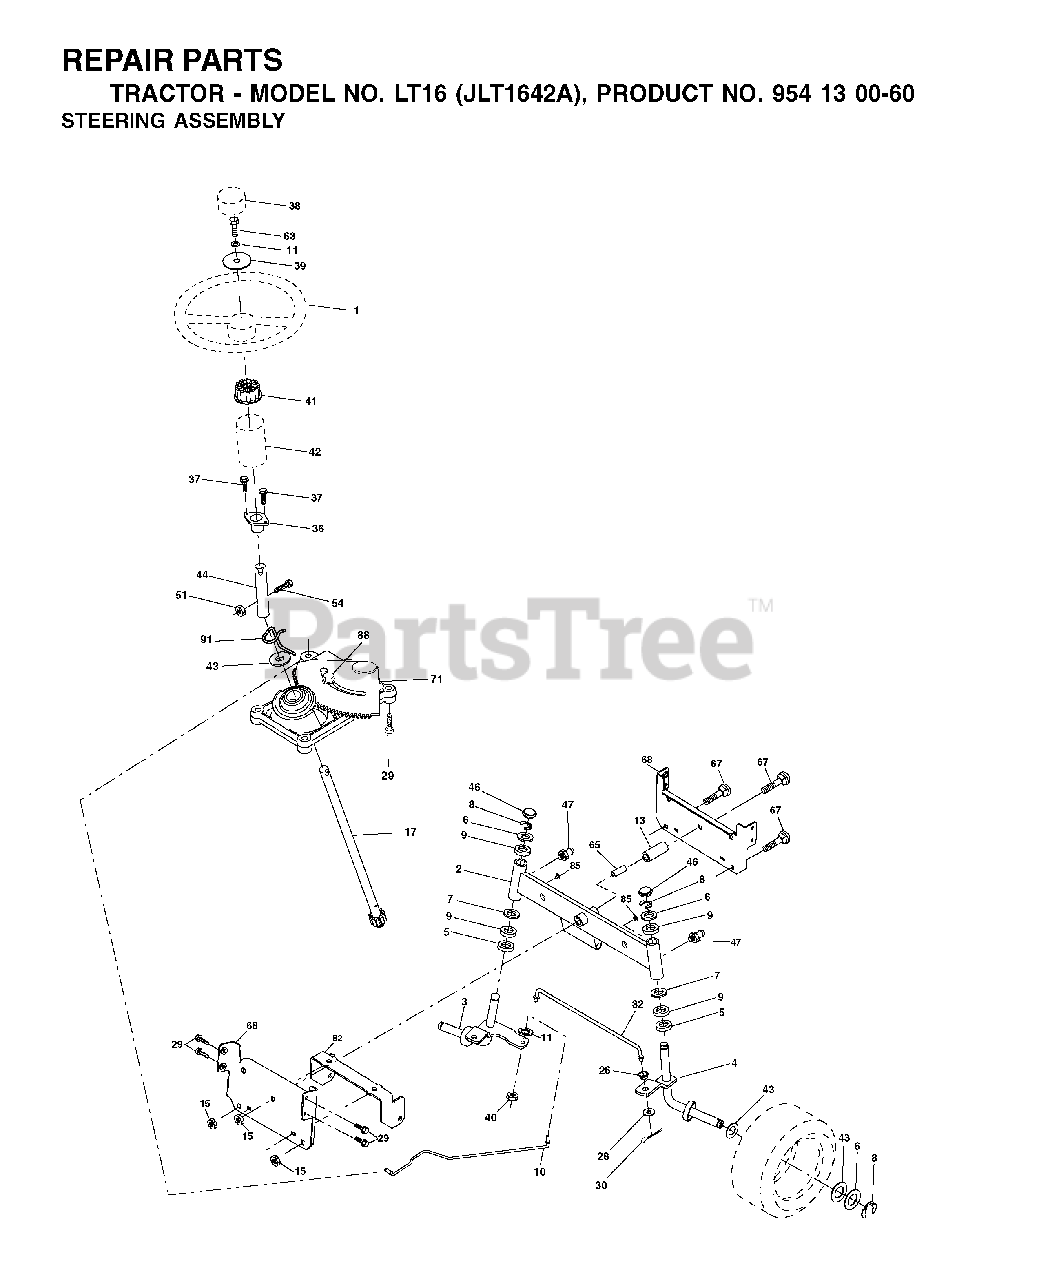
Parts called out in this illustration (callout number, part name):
2	AXLE ASM.
3	SPINDLE.ASM.LH.15"TIRES
4	SPINDLE.ASM.RH.15"TIRES
8	RING CLIP
9	BRNG T
10	DRAGLINK.15".TIRES.2001
11	WASHER, LOCK 3/8
13	TUBE, PIVOT AXLE
15	NUT
17	SHAFT ASM
26	BUSHING.DRAGLINK
28	WASHER
29	SCREW 3/8-16X3/4
30	COTTER PIN
32	TIE ROD
36	BUSHING, STEERING
39	WASHER 13/32 X 2-3/8 X 12 GA
40	GRIPCO NUT
41	STEERING WHEEL ADAPTOR
42	BOOT.STEERING.SHAFT.BLACK
44	EXT SHAFT STEERING
46	CAP.SPINDLE
47	ZERK M
51	NUT.71038.31-18.HEX.NYLOCK
54	BOLT.5/16-18X1-1/4 FULL.THREAD
65	SPACER BRACE AXLE
67	BOLT
68	BRACE.AXLE.15"TIRES
71	STEERING ASM
82	BRACKET
85	FASTENER.XMAS.TREE
88	BOLT, SHOULDER 7/16-20
91	CLIP.STEERING
